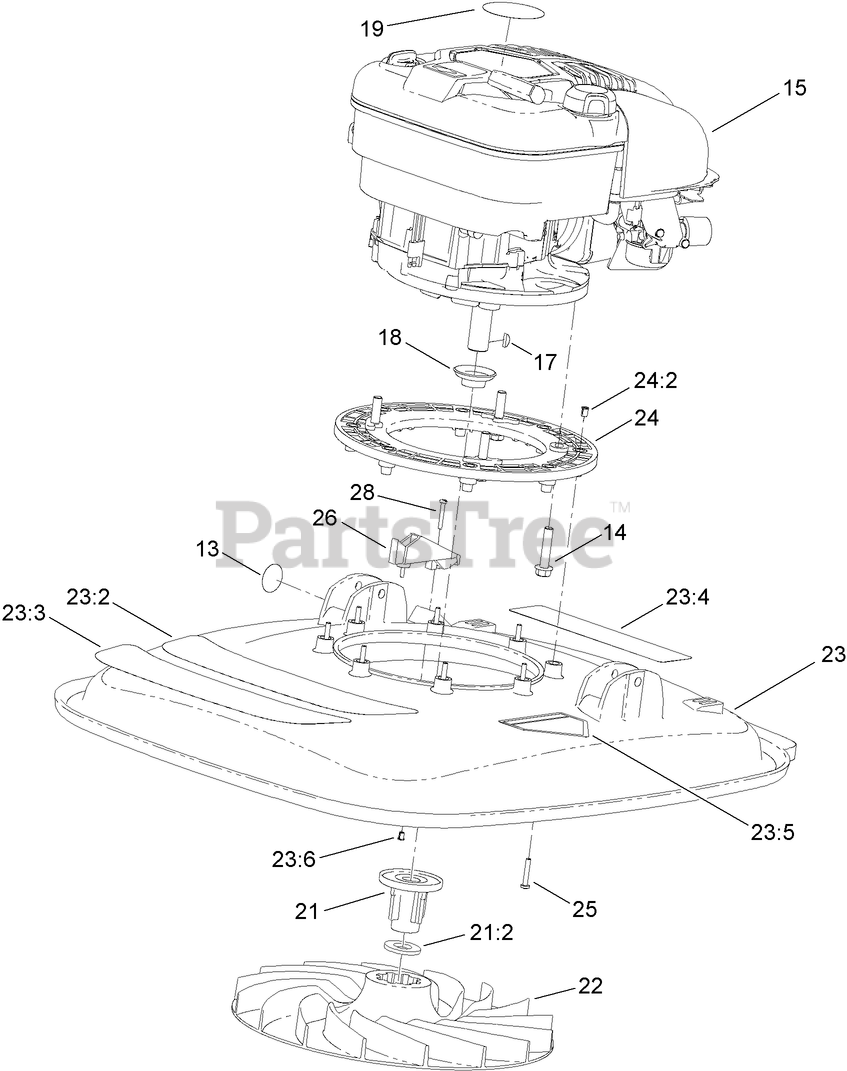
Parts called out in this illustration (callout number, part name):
13	DECAL
14	SCREW-TAPTITE
17	KEY-WOODRUFF
18	PROTECTOR-SEAL, OIL
19	DECAL-ENGINE
21	DRIVE AND SPACER ASM
21:2	WASHER-PLAIN
22	IMPELLER
23	DECK ASM
23:2	DECAL-HOVER PRO, 500 SERIES
23:3	DECAL-HOVER PRO
23:4	DECAL-WARNING
23:5	DECAL-DANGER
23:6	INSERT
24	FRAME-ENGINE
24:2	INSERT-BRASS
25	SET-SCREW
26	BRACKET
28	SCREW
